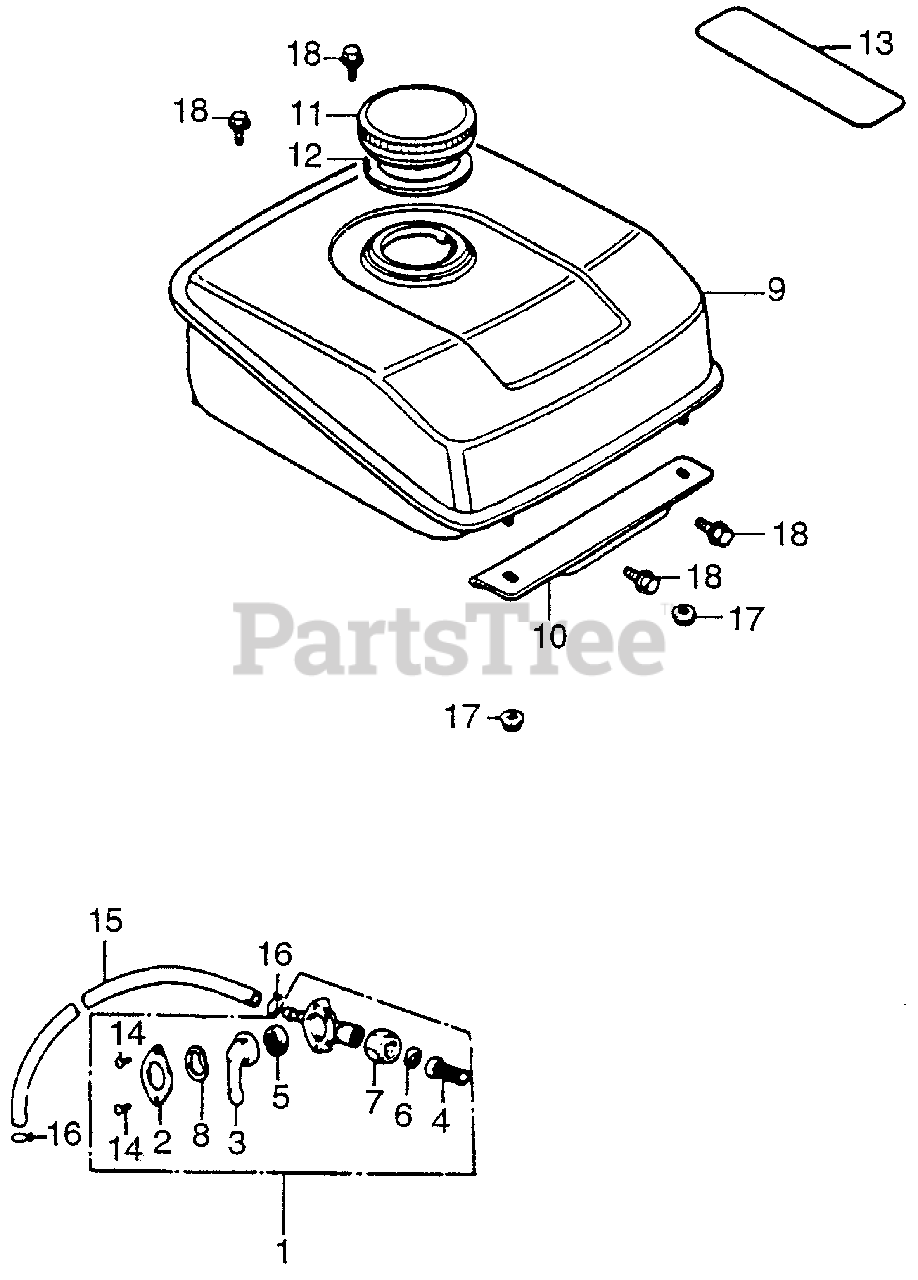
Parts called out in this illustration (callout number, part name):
1	PETCOCK ASSY. (NOT AVAILABLE)
2	COVER, PETCOCK (NOT AVAILABLE)
3	LEVER, VALVE (NOT AVAILABLE)
4	SCREEN, STRAINER
5	GASKET, VALVE
6	GASKET, FUEL STRAINER CUP
7	NUT, TURN BUCKLE (NOT AVAILABLE)
8	SPRING, PETCOCK LEVER
9	TANK, FUEL *NH31* (MCKINLEY WHITE) (NOT AVAILABLE)
10	STAY, FUEL TANK *R8* (BRIGHT RED)
11	CAP, FUEL FILLER
12	GASKET, FUEL FILLER CAP
13	MARK A, CAUTION
14	SCREW, PAN (3X6)
15	BULK HOSE, FUEL (4.5X3000) (4.5X100)
15	BULK HOSE, FUEL (4.5X3000) (4.5X110)
16	CLIP, TUBE (B8)
17	NUT, FLANGE (6MM)
18	BOLT, FLANGE (6X12)
